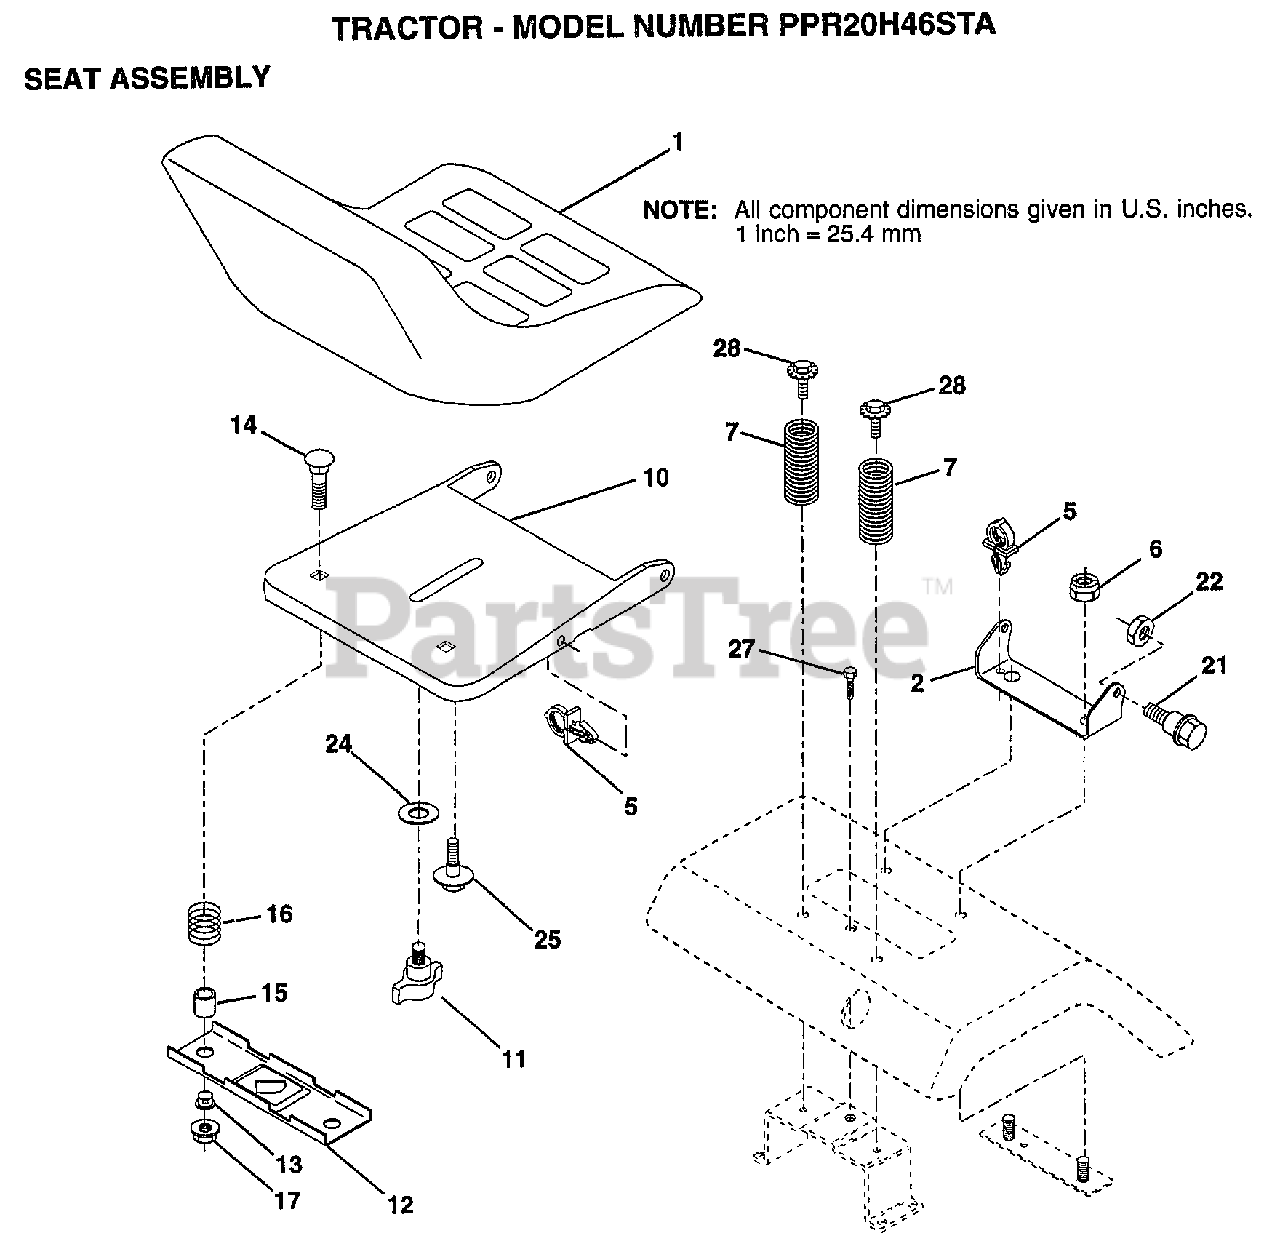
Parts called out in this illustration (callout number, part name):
1	SEAT.2500/1516.BK
2	BRACKET PVT SEAT
5	CLIP.PUSH-IN.HING
6	NUT
7	SPRING COMPRESSIO
10	PAN-SEAT
11	KNOB.SEAT.ADJ.WINGNUT
12	BRKT SWITCH
13	BUSHING
14	BOLT-RD HD SQ NK
15	SPACER SPLIT
16	SPRING COMPRESSED
21	"BOLT,SHOULDER"
22	NUT
24	WASHER
25	"BOLT,SHOULDER"
27	SCREW LT
28	BOLT.5/16-18.UNC
